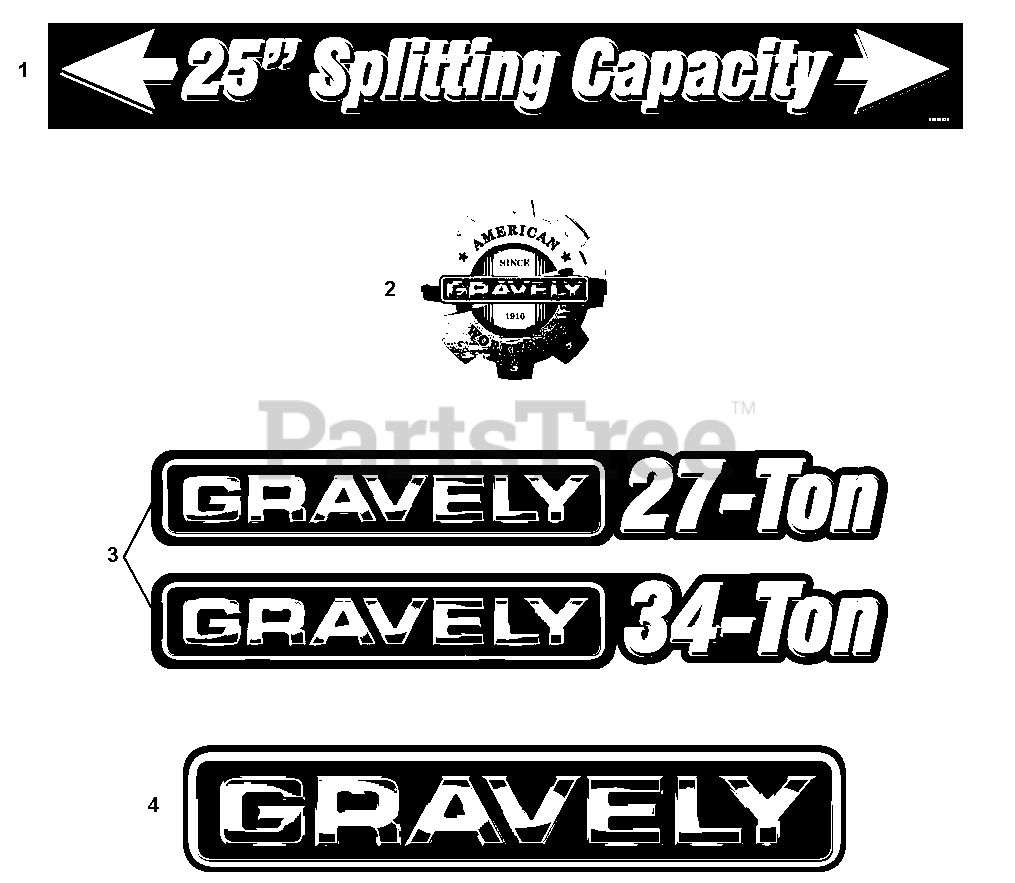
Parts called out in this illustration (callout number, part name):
1	Decal, 25" SPLIT Cap
2	Decal, Gravely Heritage, Large
3	Decal, 27TON/Gravely Logo (917003)
4	Decal, Gravely
